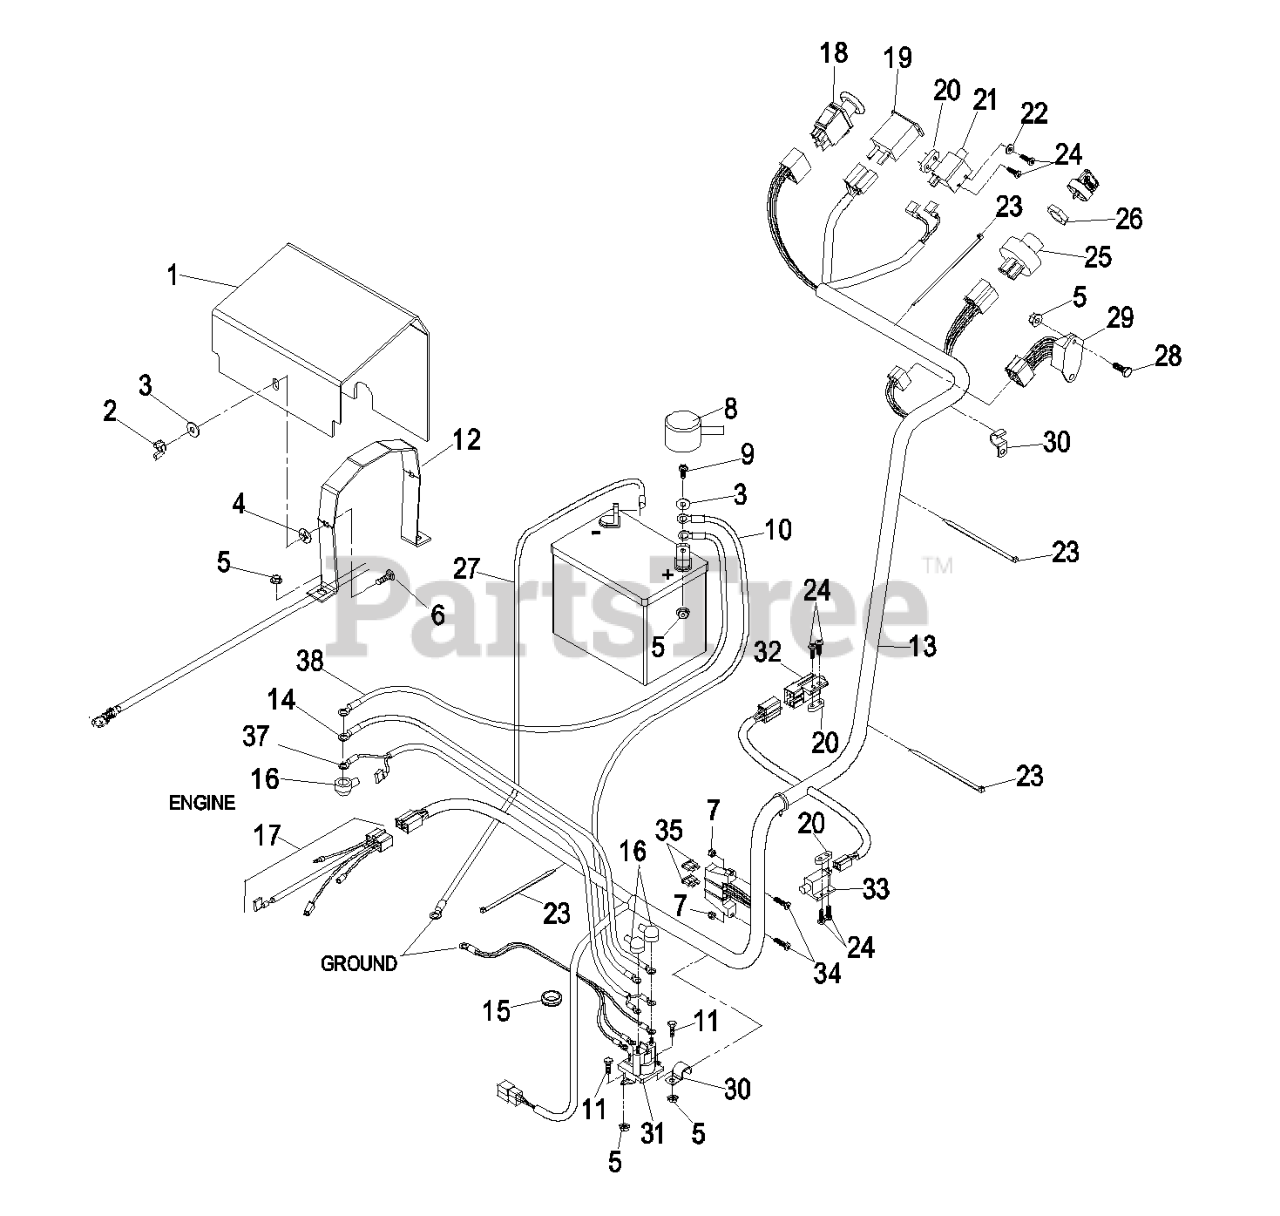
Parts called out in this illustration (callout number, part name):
1	COVER,BATTERY W/DECAL
2	NUT-WING
3	WASHER-FLAT
4	NUT-RETAINING
6	BOLT-CARR
7	NUT-LOCK, NI
8	INSULATOR-BATTERY
9	SCREW-HH
10	POSITIVE BATTERY CABLE AS
11	SCREW-HH
12	STRAP,BATTERY HOLDDOWN
13	HARNESS,TTH ECS WIRING
14	ASM,POSITIVE STARTER CABL
15	GROMMET
16	INSULATOR-SOLENOID
17	HARNESS,WIRING 19KA
18	SWITCH-PTO
19	METER-HOUR
20	PLATE-TAPPED
21	SWITCH-OPEN, NORMALLY
22	WASHER-FLAT
23	TIE-PLASTIC
24	SCREW-PPH
25	SWITCH,IGNITION
26	NUT-SWITCH, IGNITION
27	WIRE-GROUND
28	SCREW-HH
29	MODULE-OPC NO TIME DELAY
30	CLIP-HALF, LOOM
33	SWITCH-CLOSED, NORMALLY
34	SCREW-HEAD, TRUSS
35	FUSE-BLADE TYPE, 20 AMP
36	NUT-LOCK, NI
37	ASM,HARNESS TT20KCE
38	POSITIVE BATTERY CABLE AS
